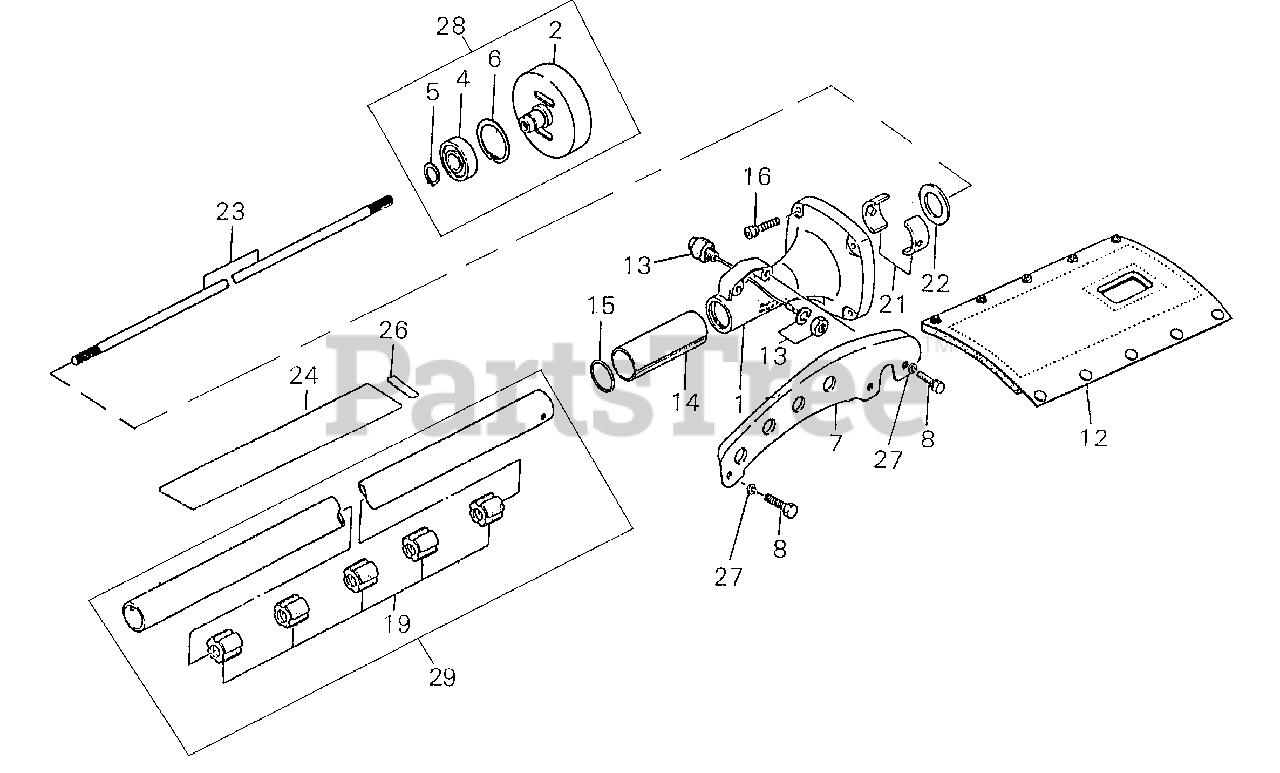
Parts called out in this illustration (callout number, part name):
1	HOUSING, CLUTCH
4	BEARING, BALL 6202 DDU
5	RING, SNAP Ø15 MM
6	RING, SNAP Ø35
7	HANGER
7	PROTECTOR
8	BOLT M6×16
12	SWITCH, ON-OFF
13	BUSHING, SWIVEL
14	O-RING
15	BOLT M6×28
16	MAIN PIPE ASSY
19	STOPPER
22	PLATE, THRUST
23	MAINSHAFT
24	LABEL, CAUTION (BLADE CAPABLE)
26	LABEL, HANDLE
27	WASHER, SPRING 6
28	DRUM ASSY, CLUTCH
28	DRUM, CLUTCH
29	BUSHING
31	LABEL,CAUTION
